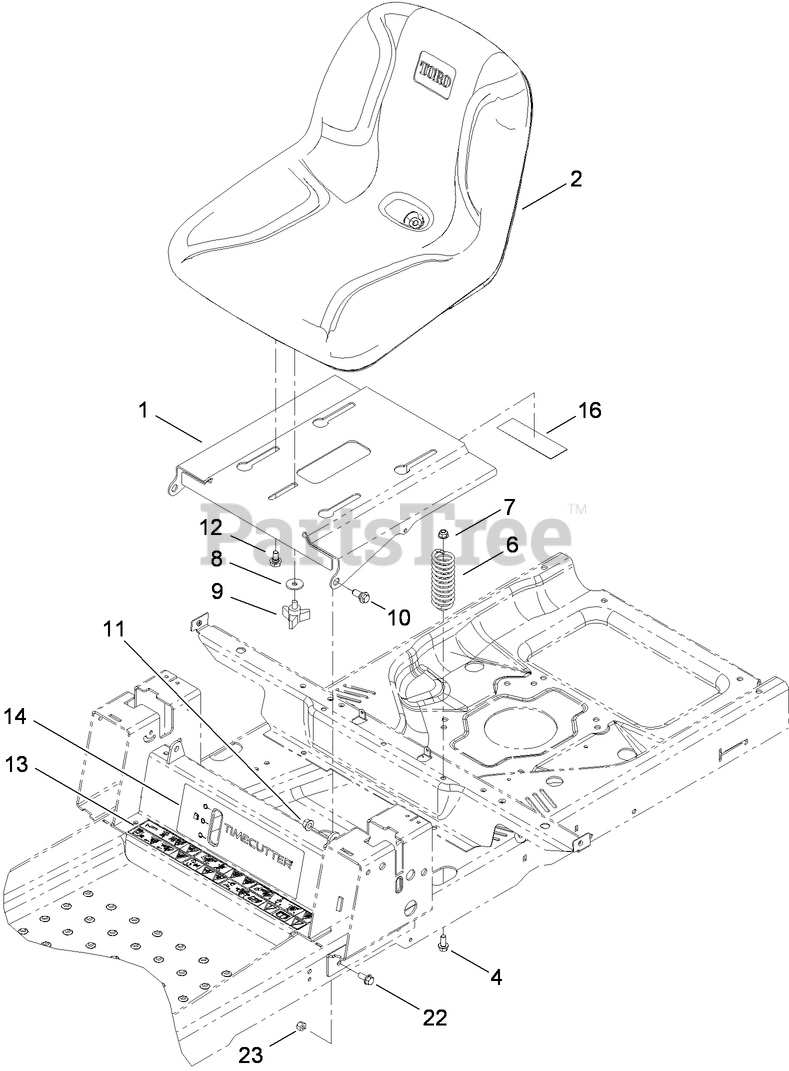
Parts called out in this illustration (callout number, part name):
1	BASE-SEAT
4	SCREW-HHF
6	SPRING-COMPRESSION
7	NUT-HF, NI
8	WASHER-PIVOT
10	BOLT-SHOULDER
11	NUT-HF
12	BOLT-SHOULDER,HFH
13	DECAL-DANGER
16	DECAL-SERVICE, CE
22	SCREW-HHF
23	NUT-LOCK, NI
